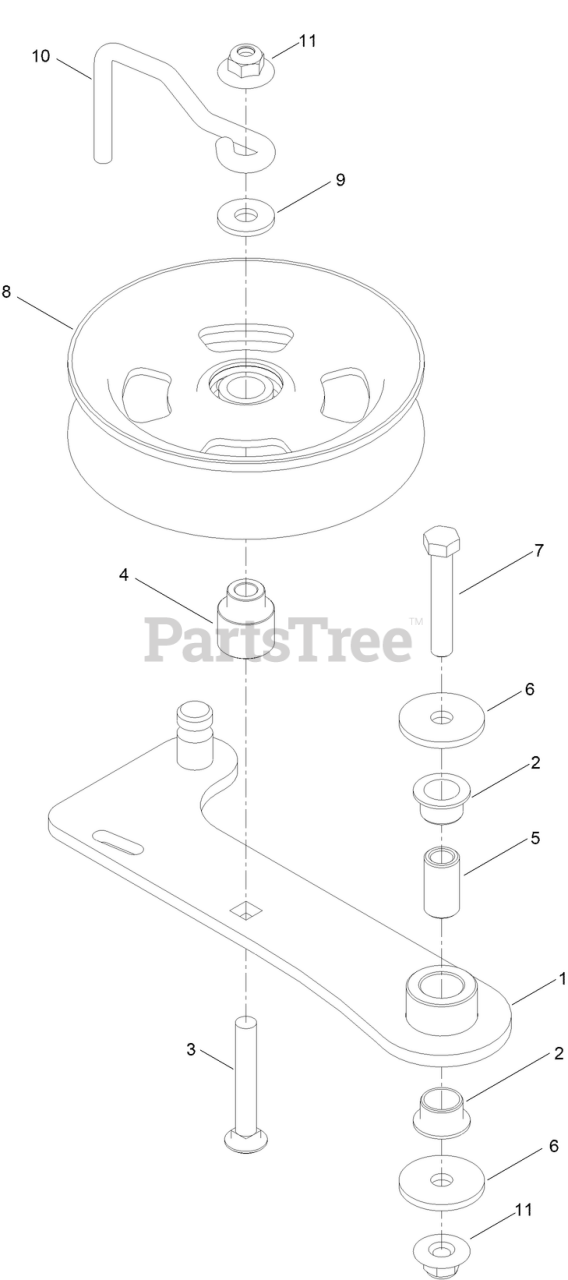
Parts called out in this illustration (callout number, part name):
1	IDLER ARM ASM
2	BUSHING-FLANGE
3	SCREW-CARR
4	BUSHING-IDLER
5	BUSHING-PIVOT, IDLER
6	WASHER
7	SCREW-HH
8	PULLEY-IDLER, FLAT
9	WASHER-HARDENED
10	GUIDE-BELT, IDLER
11	NUT-FLANGE, NI
